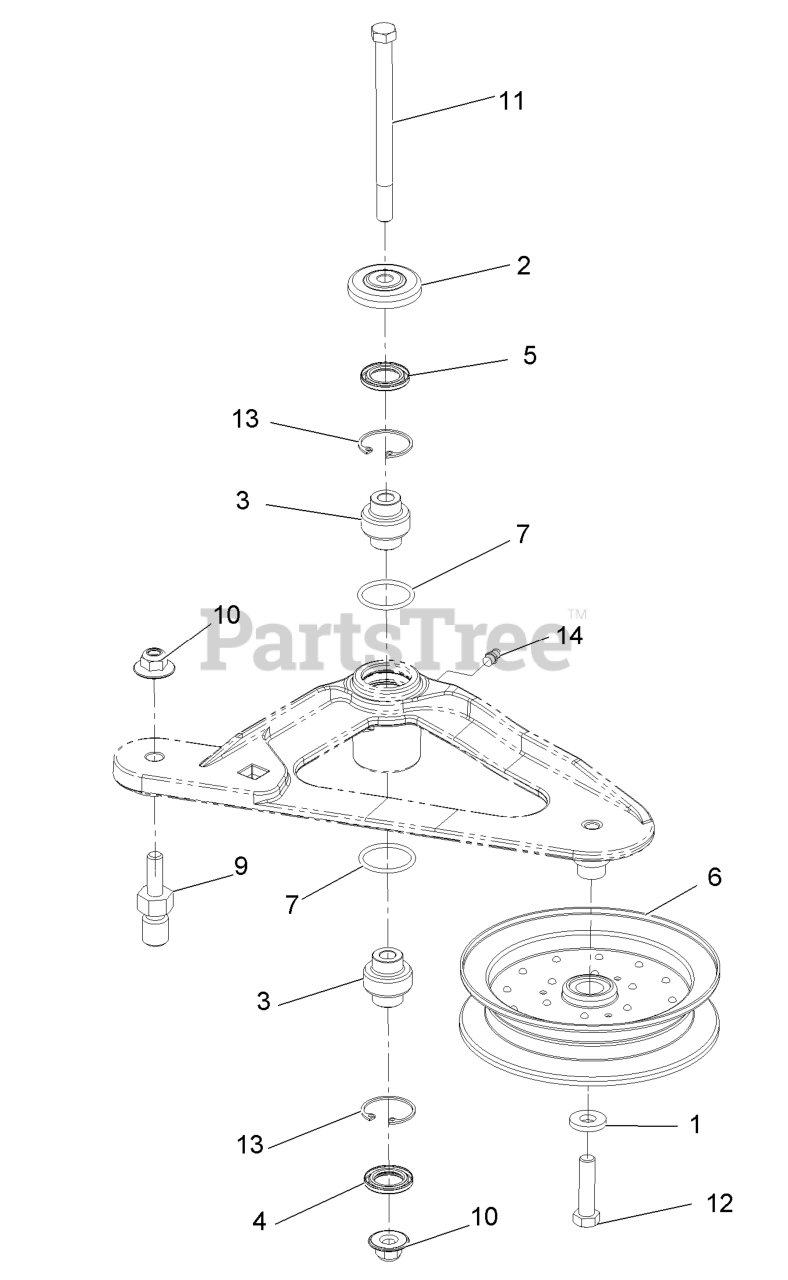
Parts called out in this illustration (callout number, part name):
2	GUARD-TOP
3	BEARING-SPHERICAL
4	SEAL-LIP, DOUBLE
5	SEAL-LIP, SINGLE
10	Nut-Nyloc 3/8-16 Flg
11	SCREW-SHOULDER, HH
12	SCREW-HH
13	RING-SNAP
14	FITTING-GREASE
